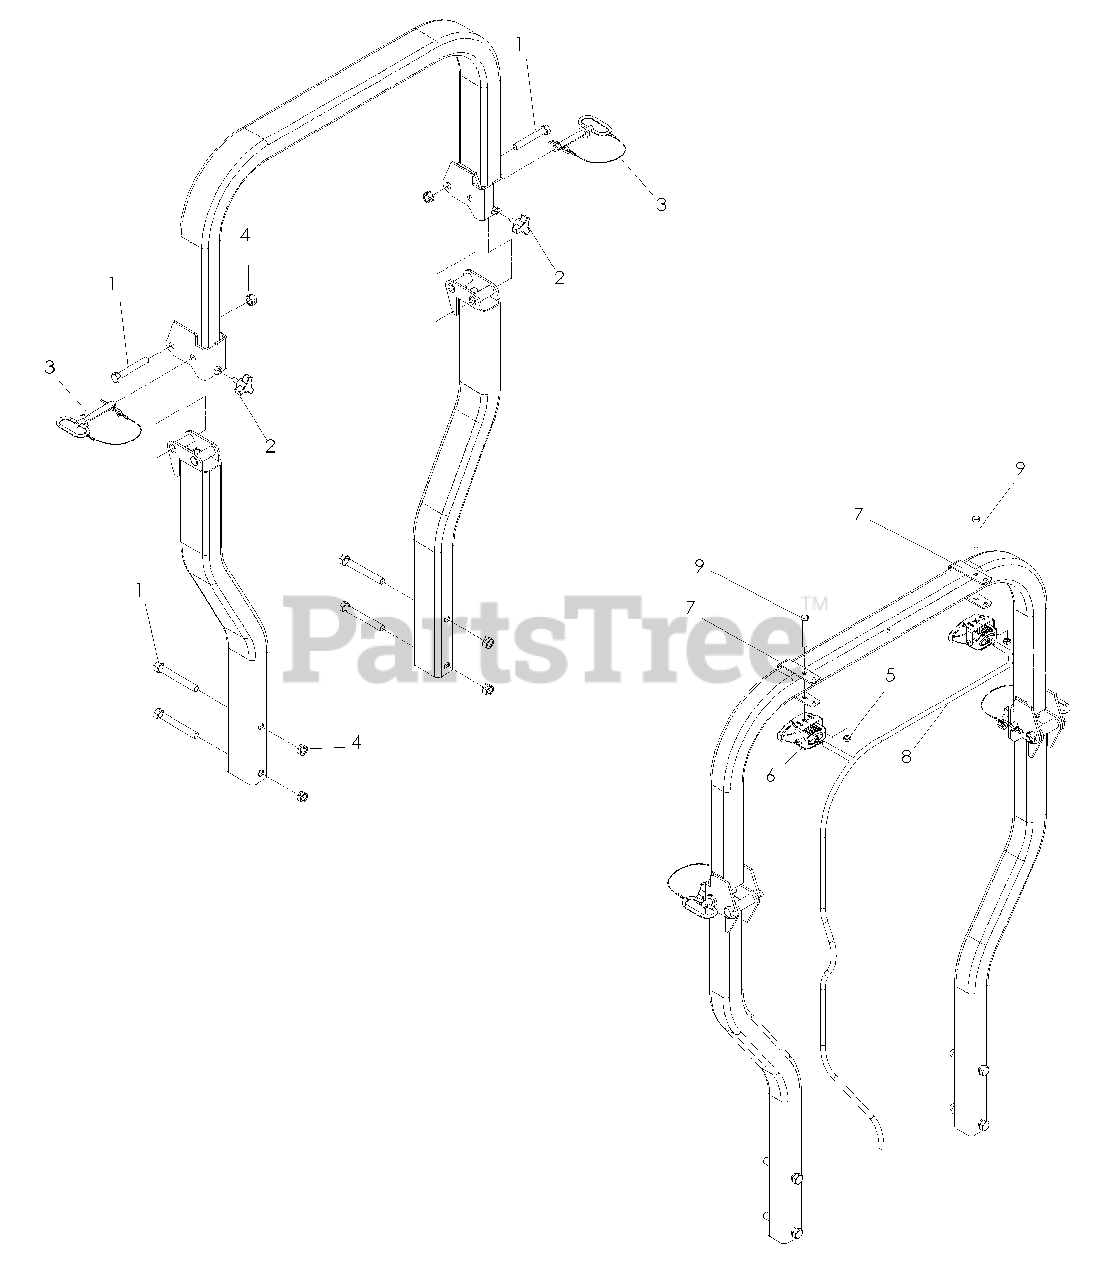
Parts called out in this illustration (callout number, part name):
1	HCS 1/4-13 x 3 1/4
2	KNOB w/STUD
3	LANYARD W/PIN 1/4"
4	NUT/4-13, CTRLK
5	NUT 5/16-18, JAM
6	LIGHT w/BRKT & HRDWARE
7	MOUNTING BRKT, LIGHT
8	LIGHT HARNESS
9	HCS 5/16-18 x 2 1/2
